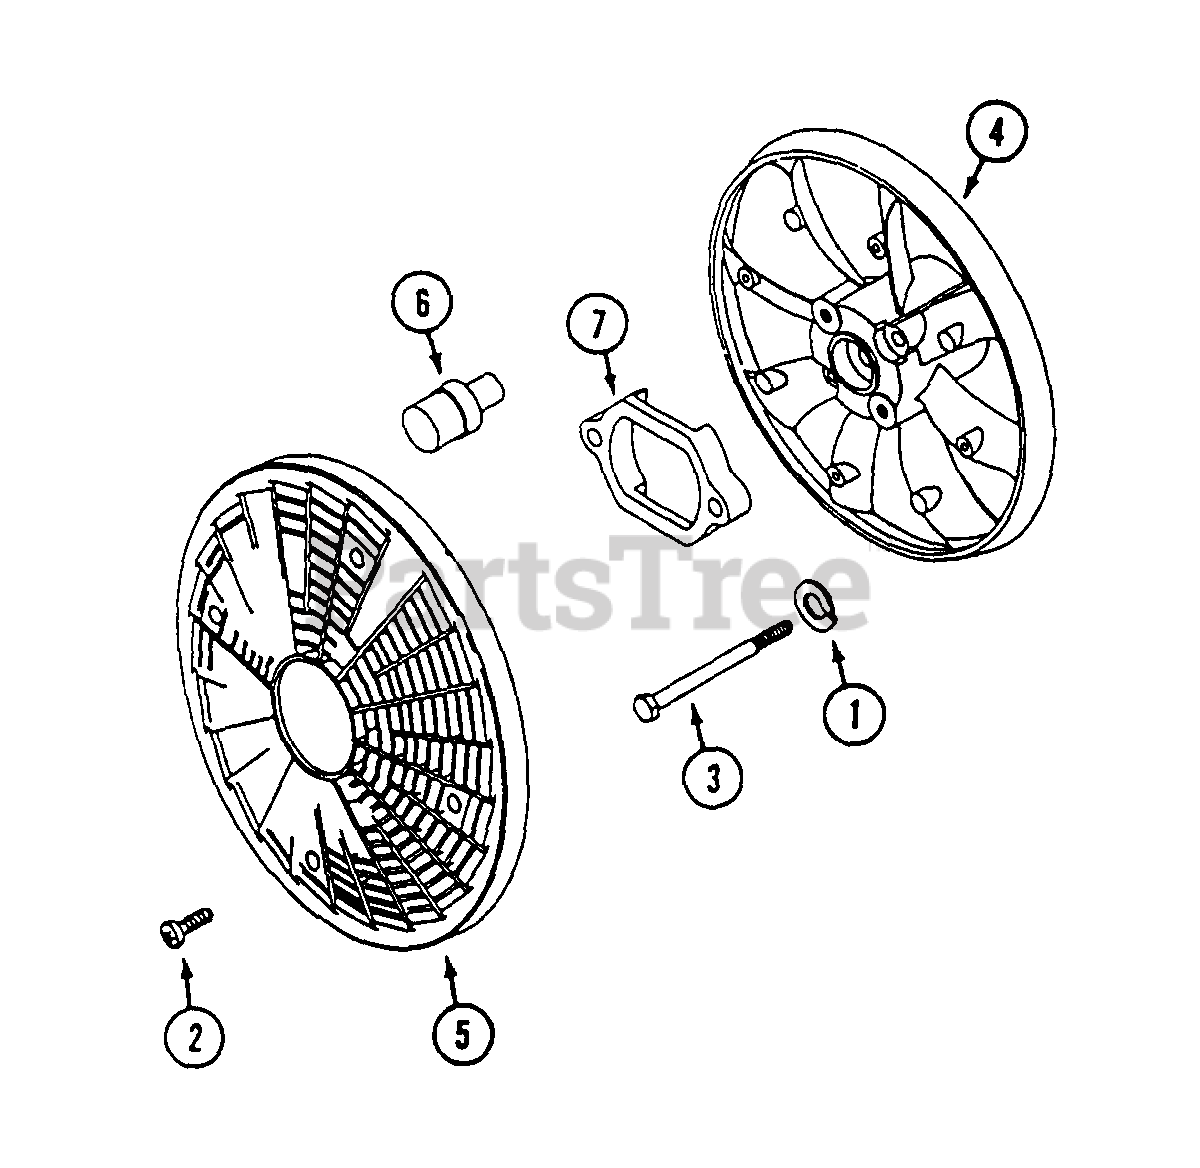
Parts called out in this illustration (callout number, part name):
2	SCREW
4	FAN - booster
5	SCREEN - rotating
